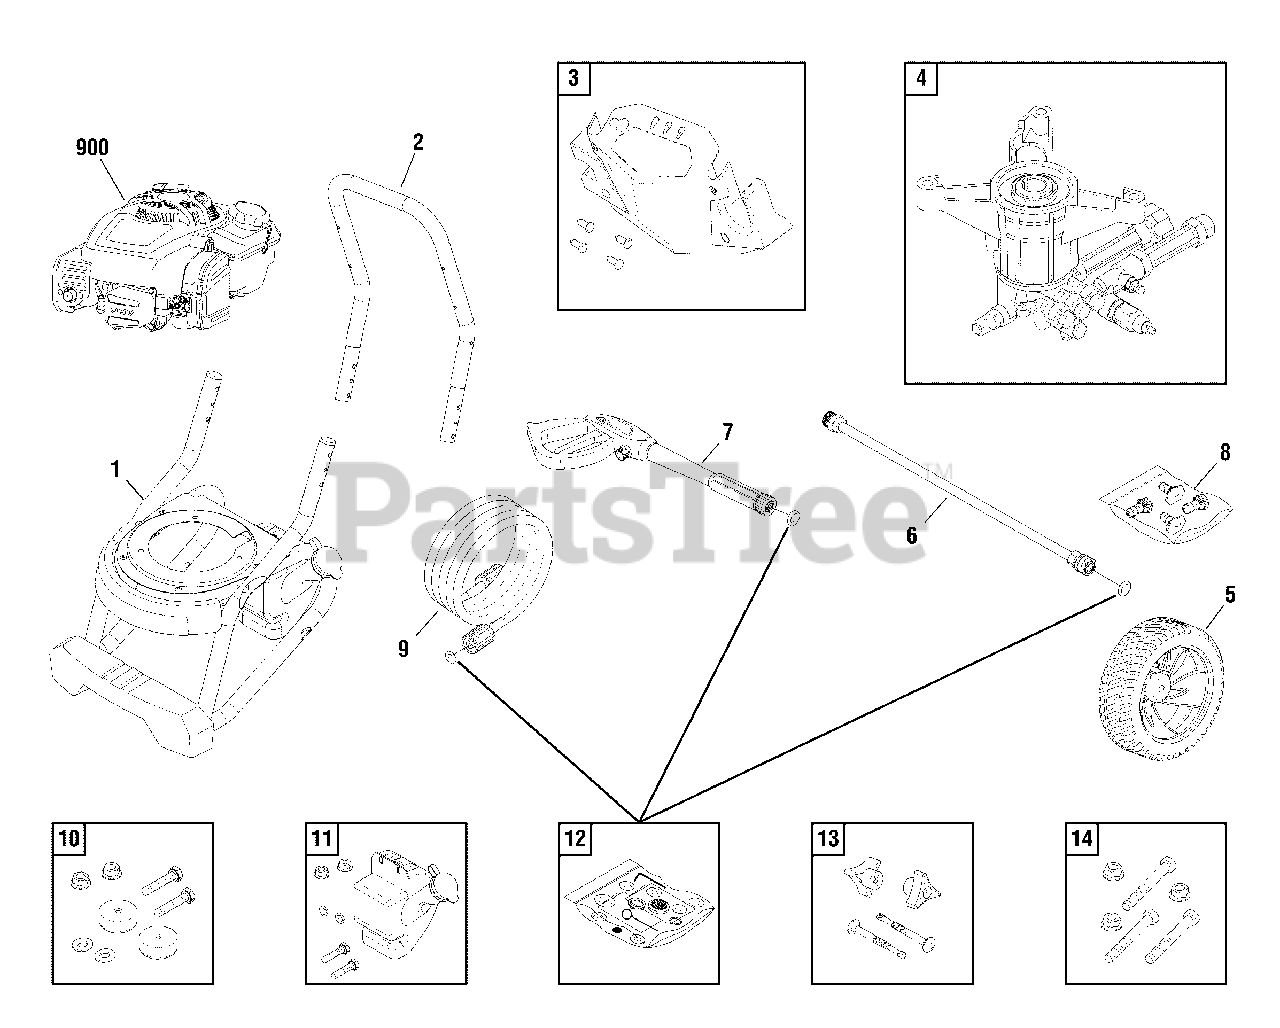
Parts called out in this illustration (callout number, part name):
4	PUMP
7	GUN
8	KIT-QC NOZZLES
9	HOSE
10	MOUNT-VIBRATION
12	KIT-O-RINGS
13	KIT-HARDWARE HANDLE
14	KIT-HARDWARE PUMP MOUNTING
